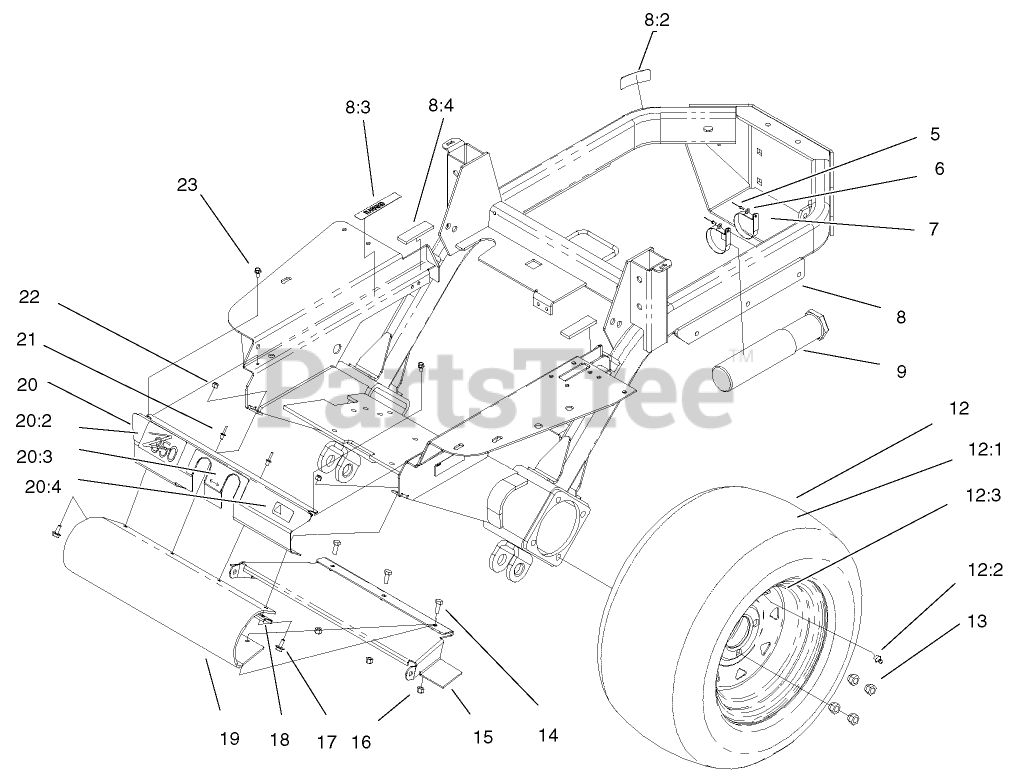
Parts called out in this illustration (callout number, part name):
5	RIVET-BLIND
6	WASHER-FLAT
7	CLAMP-R
8	FRAME ASM W/ DECALS
8:2	DECAL-HOT SURFACE
8:3	DECAL-WARNING
8:4	PAD-RUBBER
9	TUBE-MANUAL
12	Tire And Wheel ASM
12:1	TIRE
12:2	STEM-VALVE
12:3	WHEEL
13	NUT-LUG
14	SCREW-HH
15	COVER-DRIVESHAFT
16	NUT-LOCK, NI
17	SCREW-HHF
18	BRACKET-GUARD
19	GUARD-FOOTREST
20	Cover Plate ASM w/ Decals
20:2	DECAL - Z350
20:3	DECAL - OPERATION
20:4	DECAL-PROTECTION, EAR
21	RIVET-BLIND
22	NUT-HF
23	SCREW-HWH
